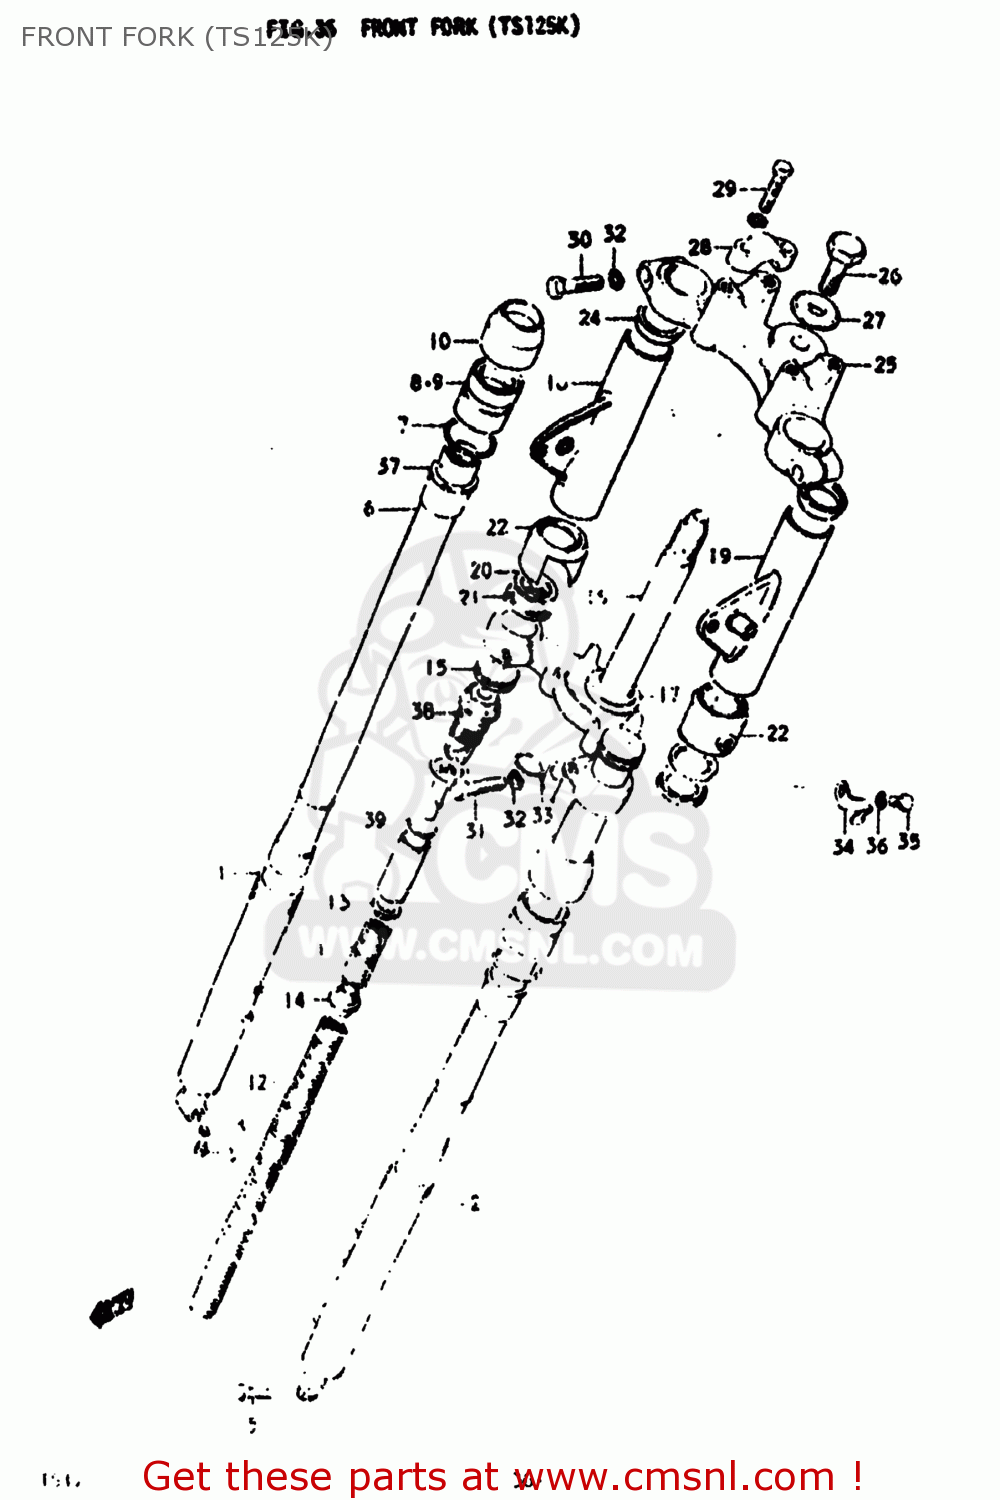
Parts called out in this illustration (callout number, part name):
1	TUBE,OUTER,RIGHT
2	TUBE,OUTER,LEFT
3	SCREW
4	GASKET,DRAIN,PLUG (NAS)
5	BOLT
6	TUBE,FORK,INNER
7	O RING,OIL SEAL LWR
8	NUT,FORK OUTER TUBE
9	SEAL,OIL
10	SEAL,DUST
11	SPRING
12	SPRING,FRONT FORK
13	GUIDE,SPRING
14	JOINT,SPRING
15	CAP,FRONT FORK
16	STEM,STEERING
17	RACE,STEERING OUTER LWR
18	BRACKET,HEADLAMP HOUSING
19	BRACKET,HEADLAMP,LEFT
20	CUSHION,HEADLAMP BRACKET
21	GUIDE, COVER
22	CUSHION,HEADLAMP BRACKET
24	SEAT,HEADLAMP BRACKET
25	HEAD,STEERING STEM
26	BOLT,FORK INNER TUBE
27	WASHER
28	HOLDER,HANDLEBAR
29	BOLT
30	BOLT,FORK INNER TUBE F
31	BOLT,FR FORK LWR(12X33)
32	LOCK WASHER
33	CLIP
34	CLIP
35	SCREW
36	LOCK WASHER
37	BUSHING,GUIDE
38	CAP
39	SEAT,SPRING
